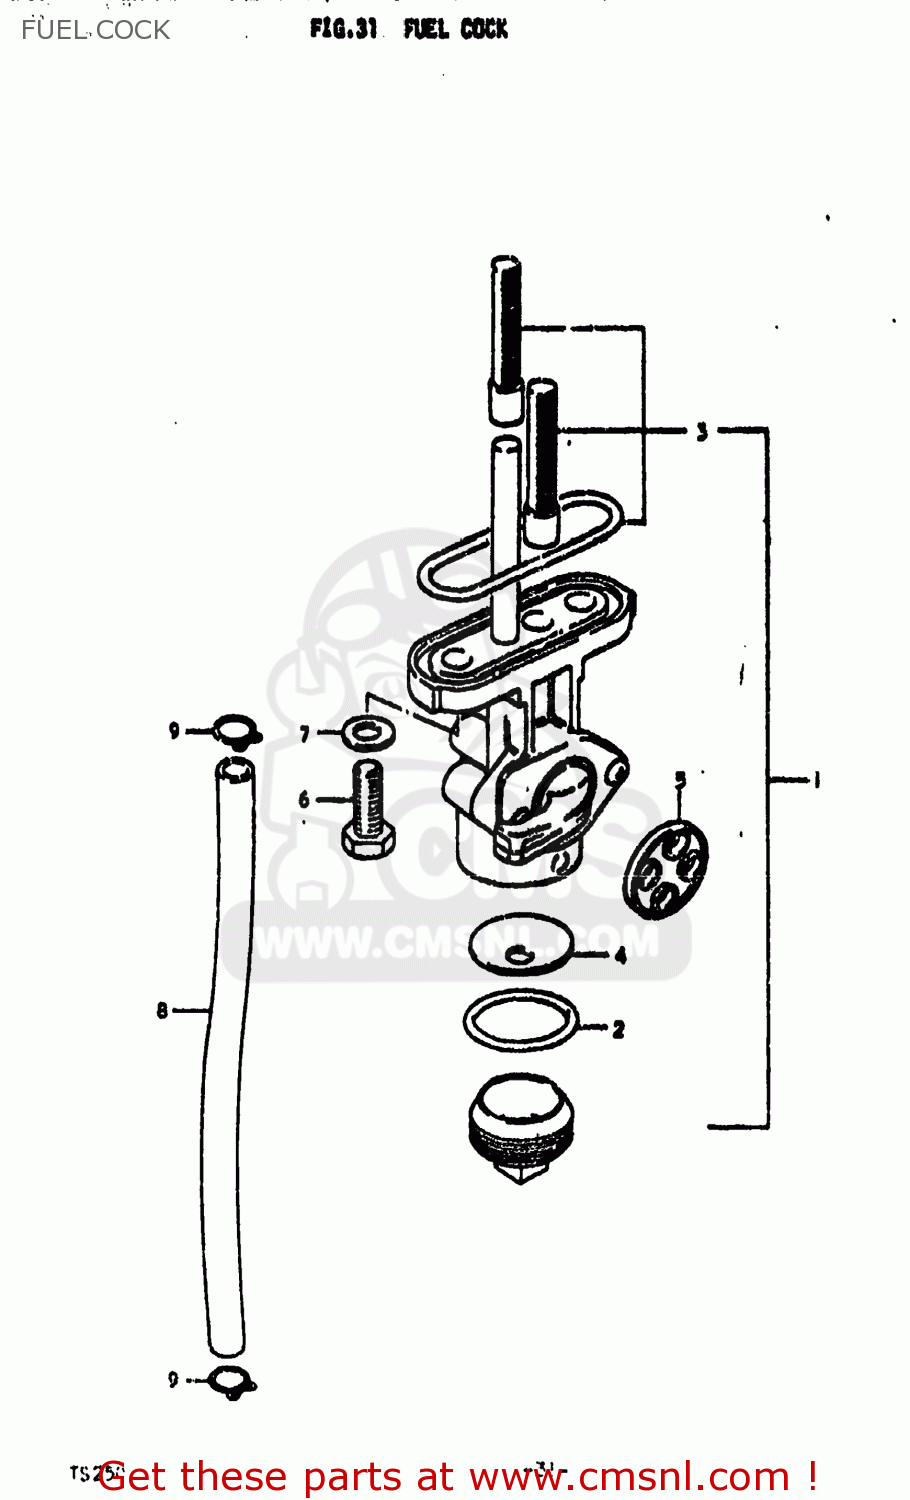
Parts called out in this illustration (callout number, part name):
1	COCK ASSEMBLY,FUEL
2	GASKET,FILTER (NAS)
3	FILTER SET,FUEL COCK
4	NET,STRAINER
5	GASKET,LEVER (NAS)
6	SCREW
7	GASKET
8	HOSE
9	CLIP
